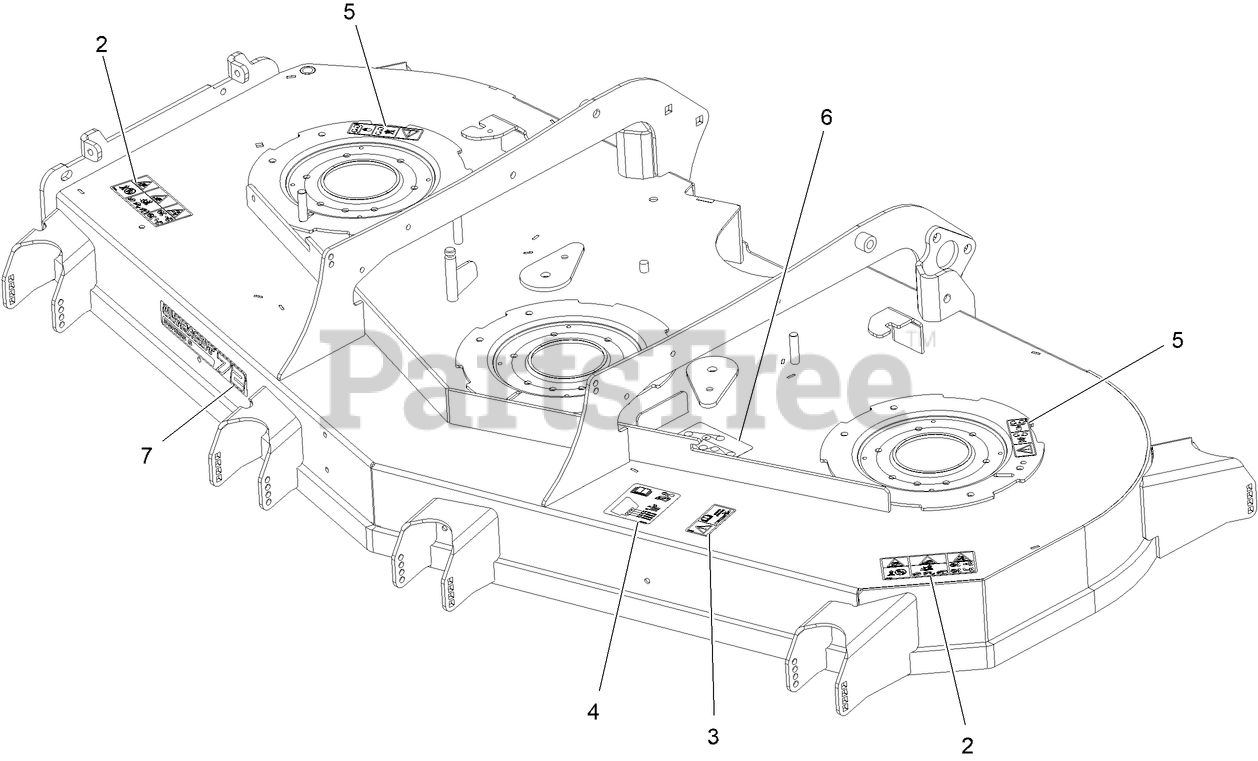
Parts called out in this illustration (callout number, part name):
2	DECAL-WARNING THROWN OBJ
3	DECAL-TORQUE, BOLT
4	DECAL-ROLLER, ANTI-SCALP
5	DECAL-COVER, MISSING
6	DECAL-BELT ROUTING
7	DECAL, 726
